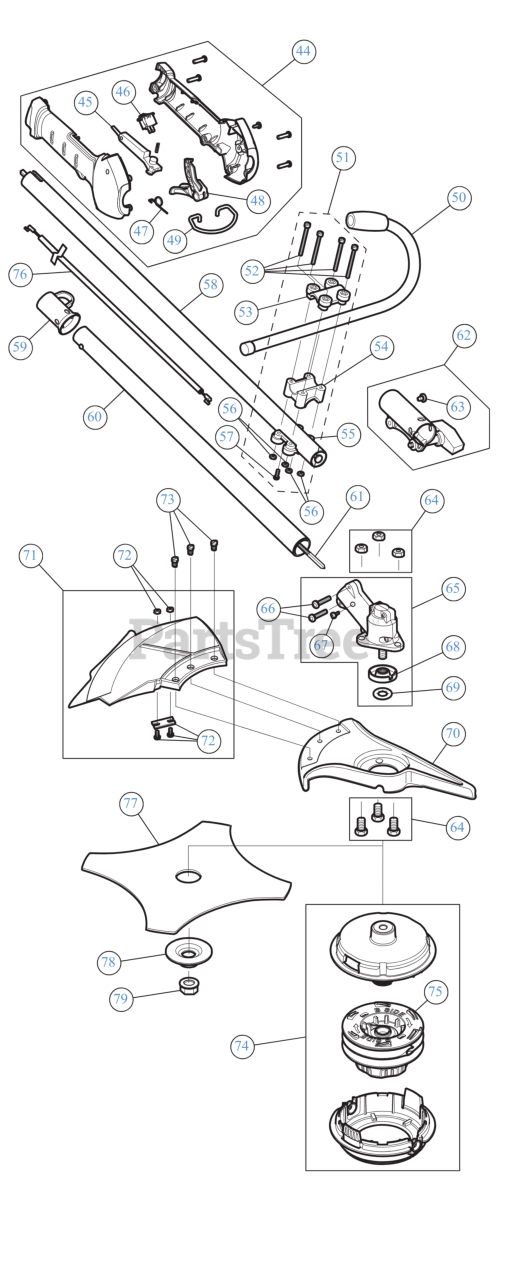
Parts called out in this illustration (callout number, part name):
44	THROTTLE GRIP ASM
45	LEVER LOCK OUT
46	SW, MOMENTARY ON/O
47	TRIGGER SPRING
48	THROTTLE TRIGGER
49	SHOULDER STRAP CLIP
50	HANDLE ASSEMBLY-JAY
51	HANDLE BRACKET ASSEMBLY
52	CLAMP SCREW
53	HANDLE UPPER CLAMP
54	HANDLE MIDDLE CLAMP
55	HANDLE LOWER CLAMP
57	SCREW, 8-32 x .312 P
58	BOOM ASSEMBLY UPR
60	BOOM ASSEMBLY LOWER
61	LOWER DRIVE SHAFT
62	SPLIT BOOM COUPLER KIT
63	SCREW, 10-32X.250 TA
64	SCREW SET-GUARD MT
65	GEARBOX ASSEMBLY
67	SCREW, 8-32 x .312 P
68	SPACER-GEARBOX
69	PALNUT:3/8" DIAM
70	SHIELD-BLADE CAST
71	SHIELD ASSEMBLY WITH BLADE
72	BLADE ASSEMBLY
73	SCREW-GUARD MTG PK
74	HEAD ASSEMBLY CNT/AF (LH) LRG
76	THROTTLE CABLE
77	BLADE 4-TOOTH
78	WASHER-BLADE CLAMP BRUSH CUT
79	BLADE LOCK NUT
